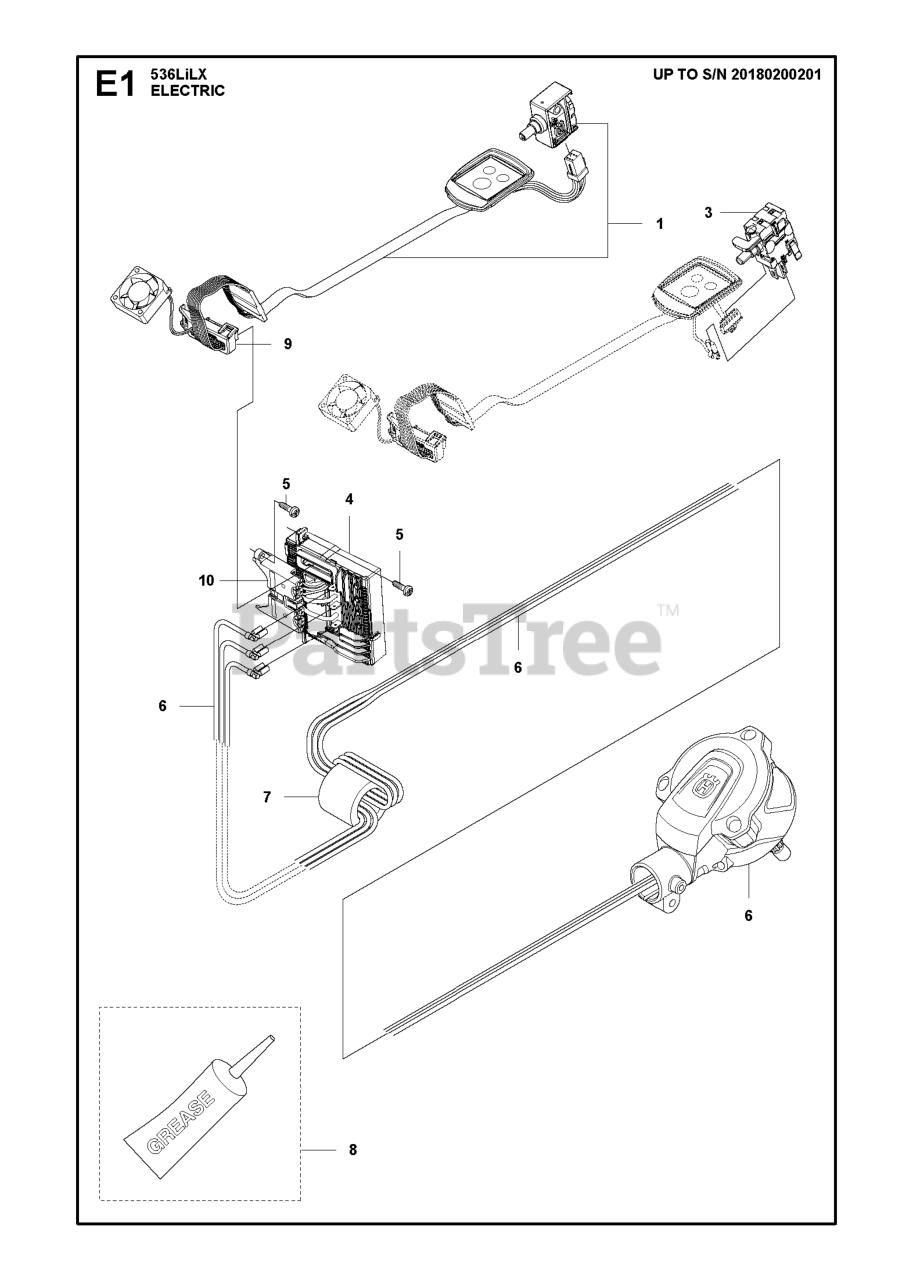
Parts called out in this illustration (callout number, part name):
1	SWITCH KIT BATTERY TRIMMER 536
3	TRIGGER SWITCH
4	CONTROL UNIT
6	MOTOR ASSY BLDC BLADE
7	FERRITE CORE
8	GREASE TUBE Q8 RUYSDAEL WR2
10	CONNECTOR BATTERY
